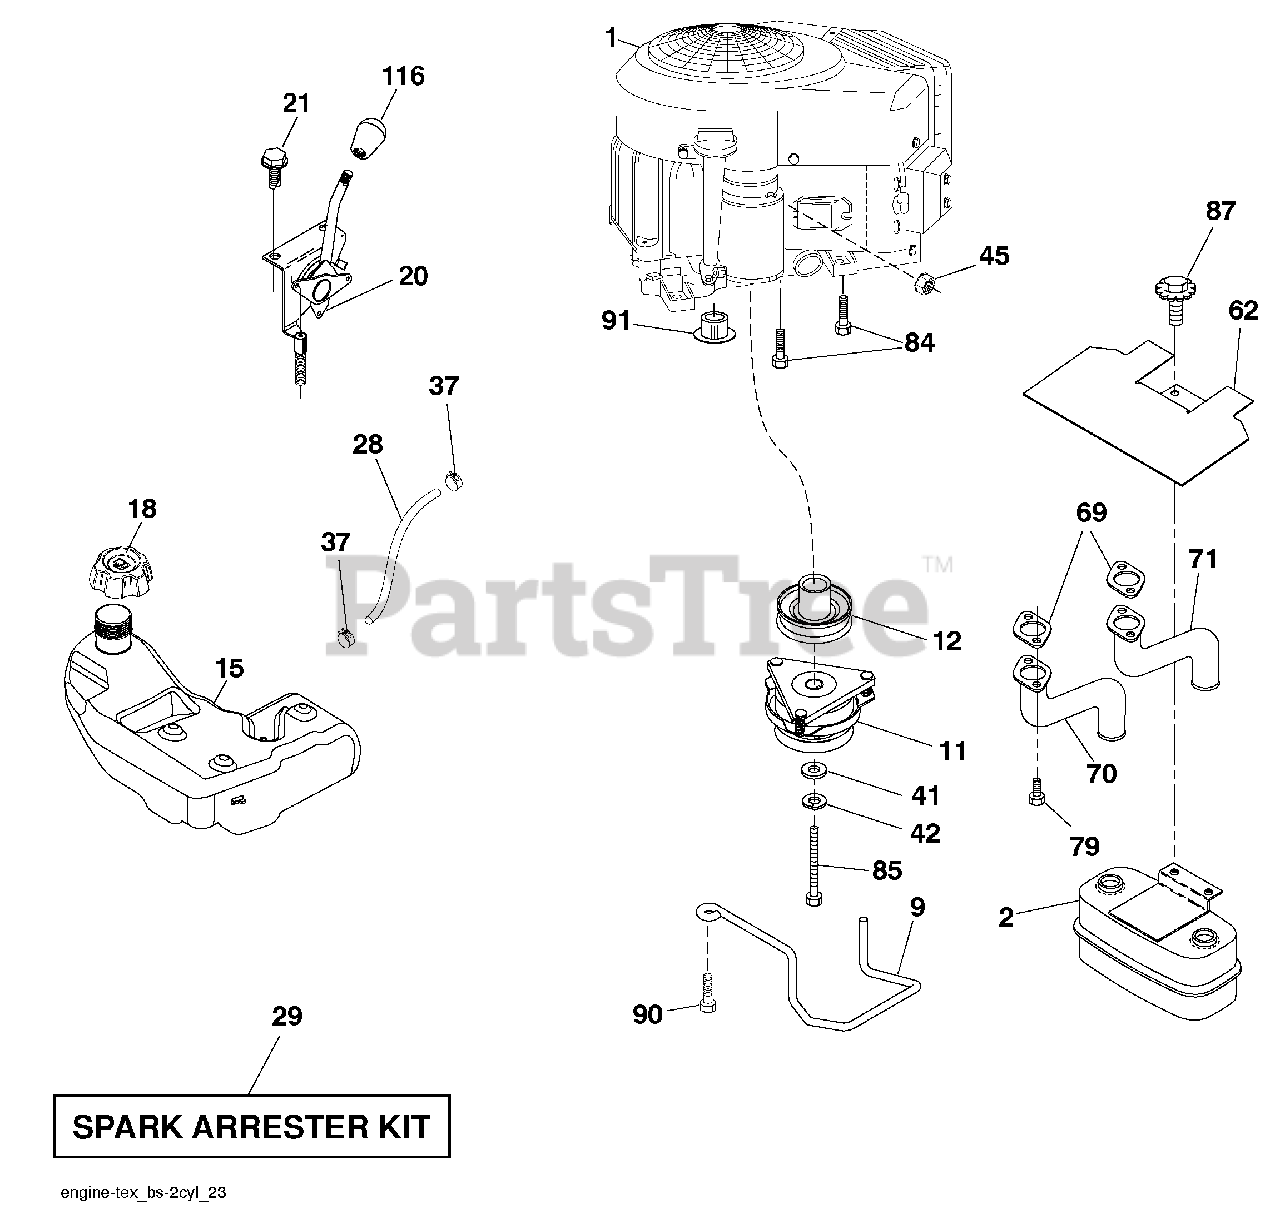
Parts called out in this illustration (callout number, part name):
9	Keeper Belt Engine
11	Clutch
12	Pulley Engine
15	Tank Fuel
18	Cap Asm Fuel
20	Control Throttle/Choke
21	Screw #10 x .750 BOS Thread
28	Fuel Line
29	Spark Arrester Kit
37	Clamp Hose
41	Washer 1-1/2 OD x 15/32 ID x .250
42	Washer Lock 7/16
45	Nut Keps Hex 1/4-20 unc
62	Heat Shield
70	Exhaust Tube LH
71	Exhaust Tube RH
79	Screw Socket Head 5/16-18 x1
84	Screw 3/8-16 x 1-1/4
85	Bolt Hex 7/16-20 x 4 x Gr. 5-1.5 Thr
87	Bolt 5/16-18 unc x 3/4 w/Sems
90	Screw 3/8-16 x 1
116	Knob Soft Touch
